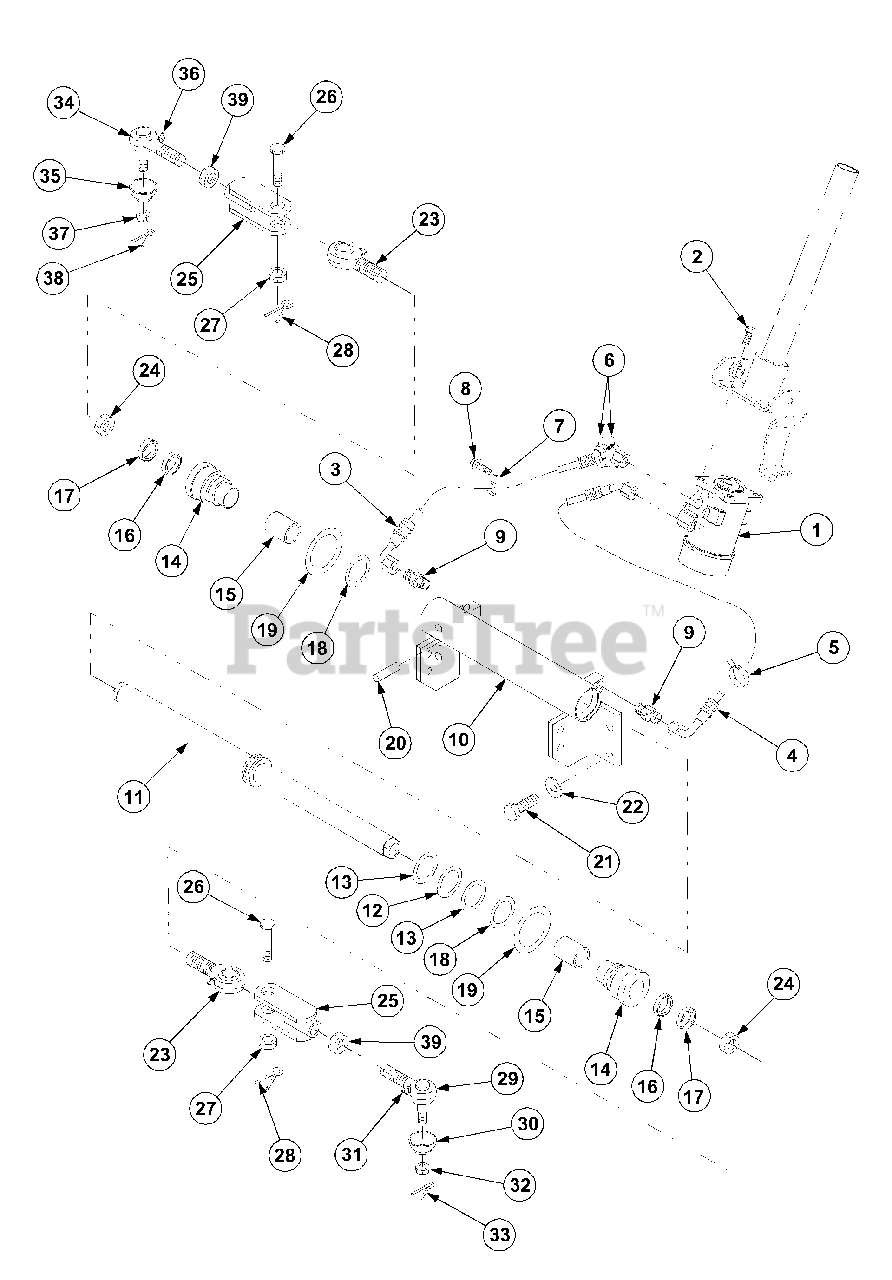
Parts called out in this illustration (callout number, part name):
1	Steering Unit
2	Bolt,w/Washer
8	Bolt,w/Washer
10	Tube,Cylinder
31	Nipple,Grease
34	Socket Assy
36	Nipple,Grease
